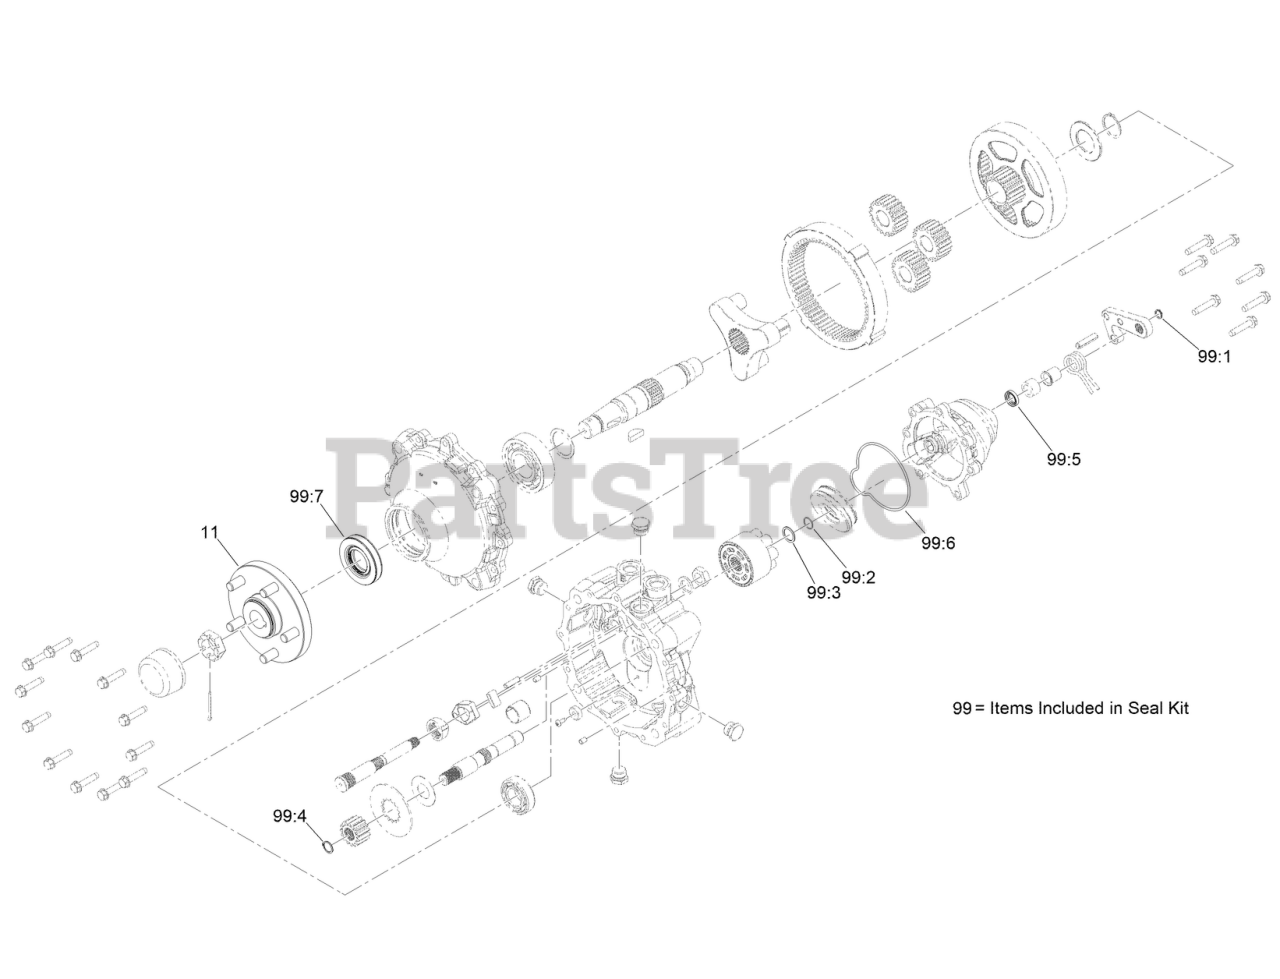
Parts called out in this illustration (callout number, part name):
11	5 STUD WHEEL HUB KIT
99	SEAL KIT
99:1	RETAINER RING
99:2	RING-RETAINING
99:3	WASHER
99:4	RING-RETAINING
99:5	SEAL, BRAKE
99:6	O-RING, ROUND
99:7	SEAL, AXLE
